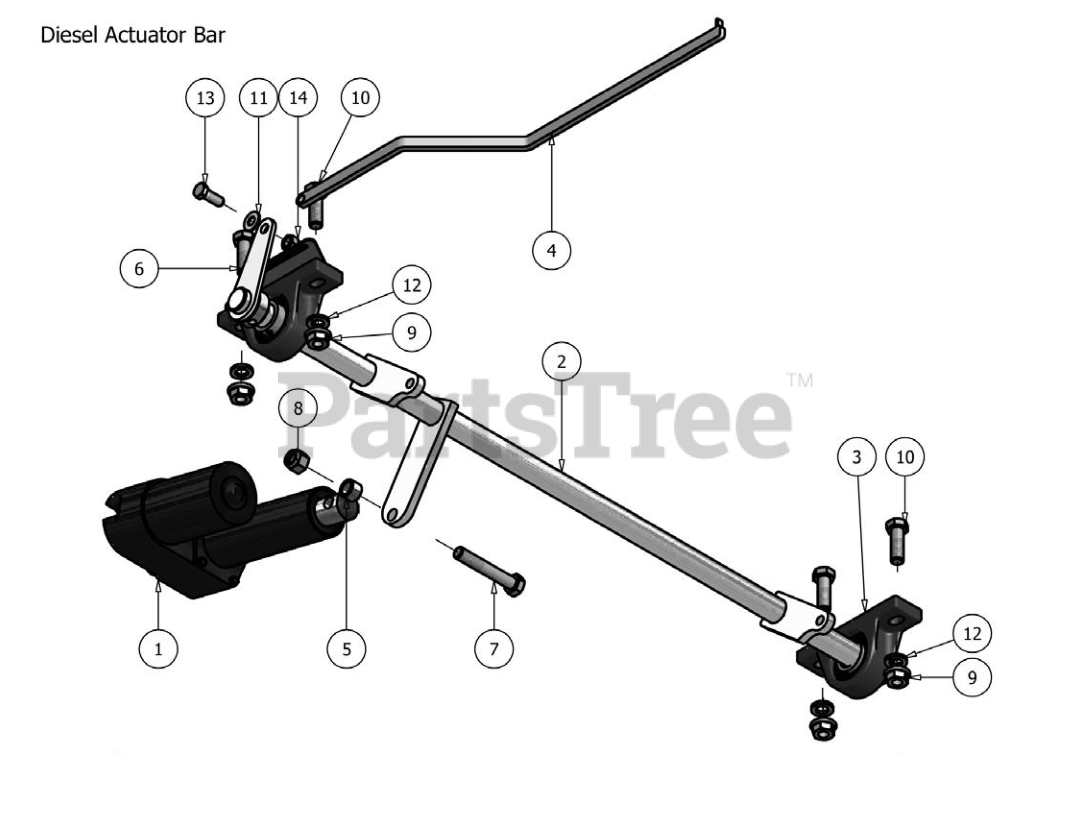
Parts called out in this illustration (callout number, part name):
2	Actuator Bar
3	1" Pillow Block
4	Height Indicator
5	1/2" Washer
6	2006 Height Indicator Lever
7	1/2" x 2 1/2" Hex Bolt
8	1/2" Nylock Nut
9	1/2" Flange Nut
10	1/2" x 1 1/2" Hex Bolt
11	.360 ID Plastic Washer
12	1/2" Lock Washer
13	3/8" x 1" Hex Bolt
14	3/8 Nylock Nut
